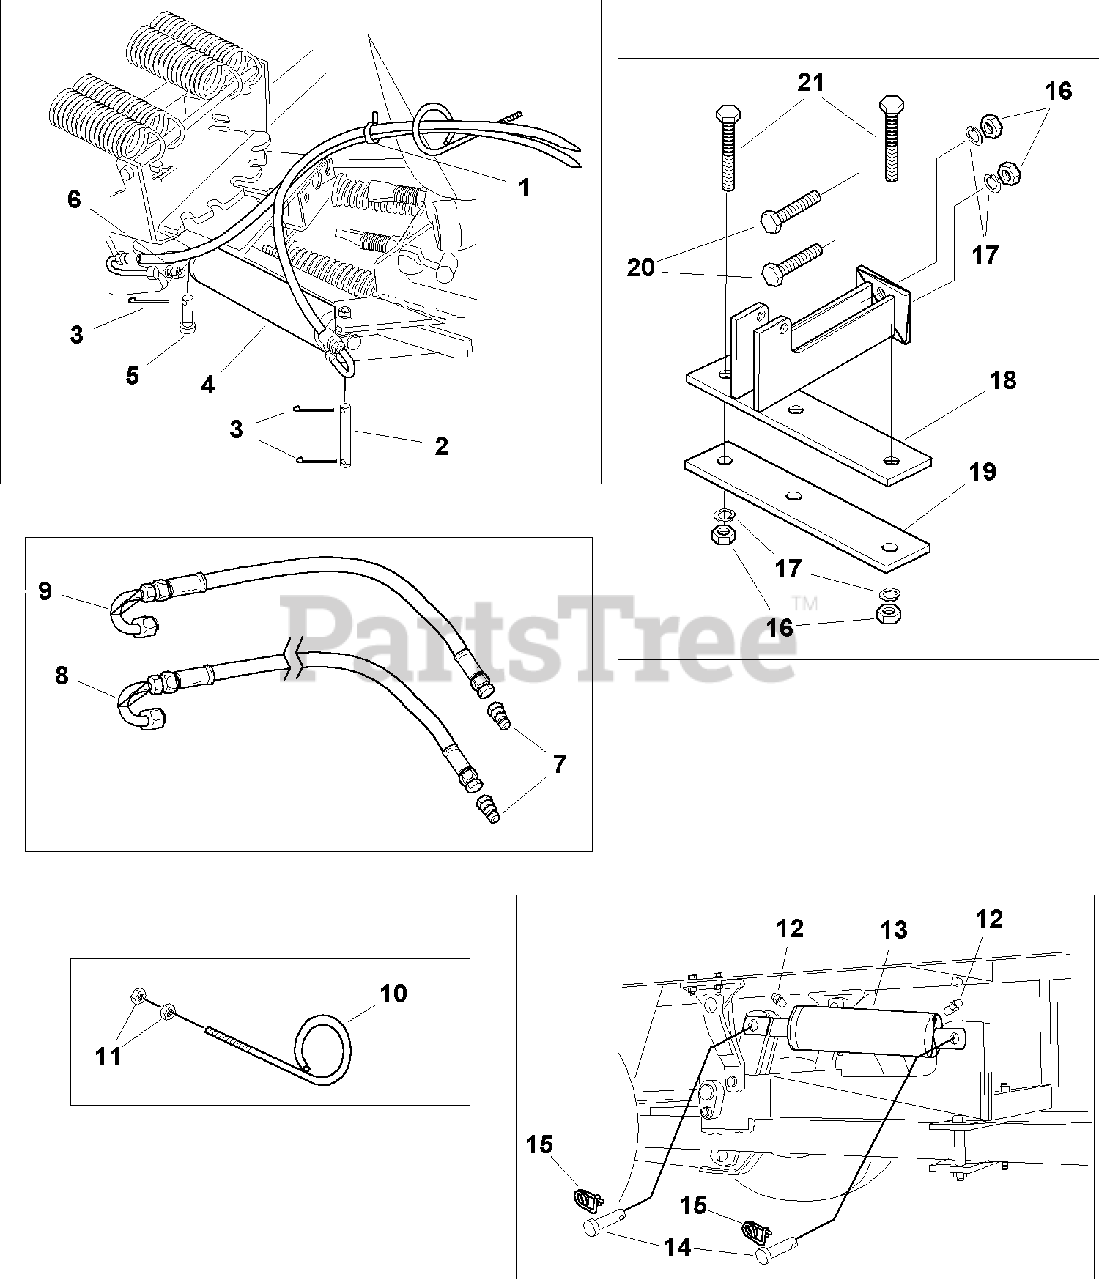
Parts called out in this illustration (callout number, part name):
1	TIE, Self Locking
3	PIN, Cotter
4	ANGLING CYLINDER ASSEMBLY
5	PIN, Flat Head, Drilled, 5/8 x 1-5/8
7	NOSE PIECE ASSEMBLY
8	HOSE ASSEMBLY, Length 17.0"
9	HOSE ASSEMBLY, Length 50.0"
10	HOSE SUPPORT
11	NUT, Hex, 5/16-18
12	TUBE FITTING, Male
13	LIFT CYLINDER ASSEMBLY
14	PIN, Clevis
15	PIN, Retainer
16	NUT, Hex, 1/2-13
17	LOCKWASHER, 1/2
18	SUPPORT ASSEMBLY, Cylinder
19	CLAMP, Plate
20	CAPSCREW, Hex Head,1/2-13 x 1-1/2
21	CAPSCREW, Hex Head,1/2-13 x 3-1/2
